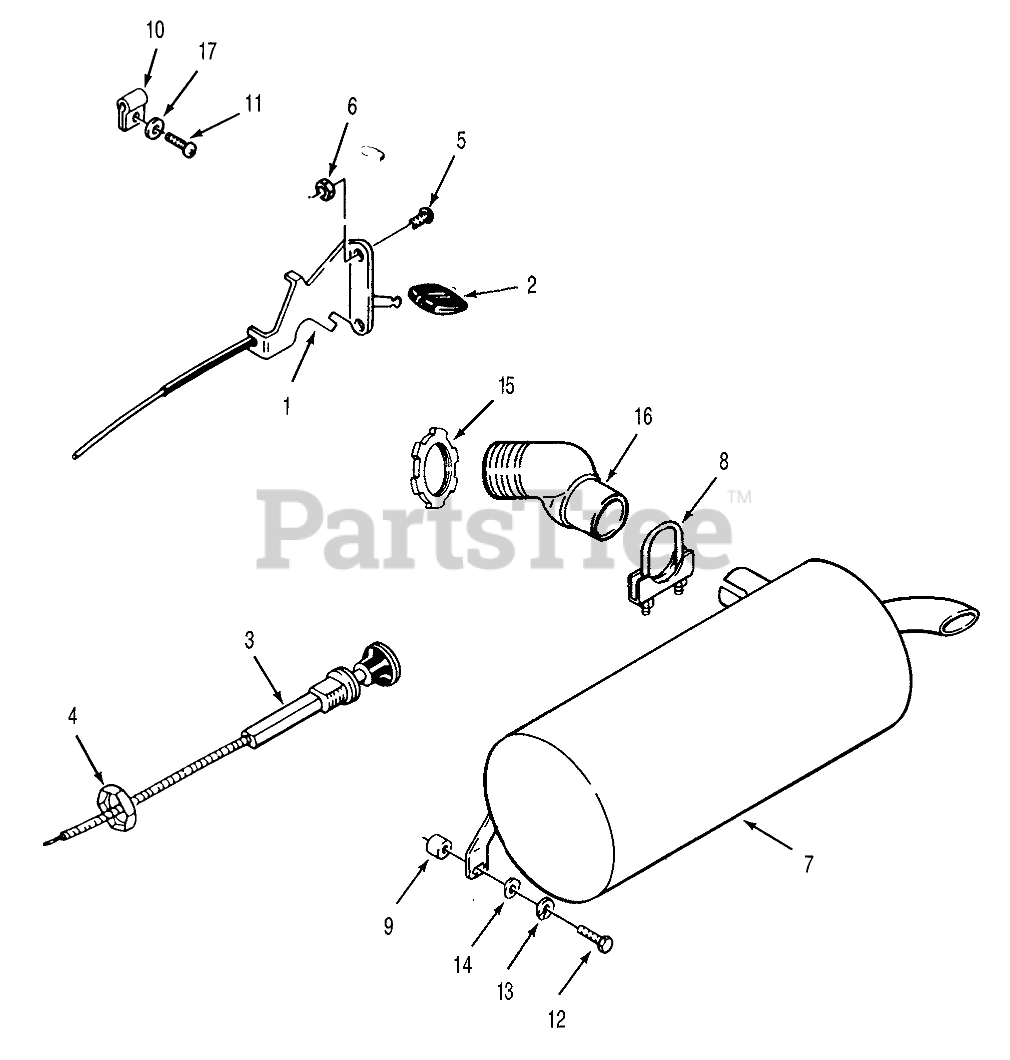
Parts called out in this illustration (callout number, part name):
1	CONTROL-THROTTLE
2	KNOB-CONTROL
3	CONTROL CHOKE
4	NUT-HEX PALNUT
5	SCRW-PHC
6	Nut
7	Muffler
8	CLAMP-1 1/2
9	SPACER
11	Screw
12	Bolt
13	Lockwasher
14	WASHER 5/16 SAE
15	Nut-Lock
16	Elbow
17	Washer
